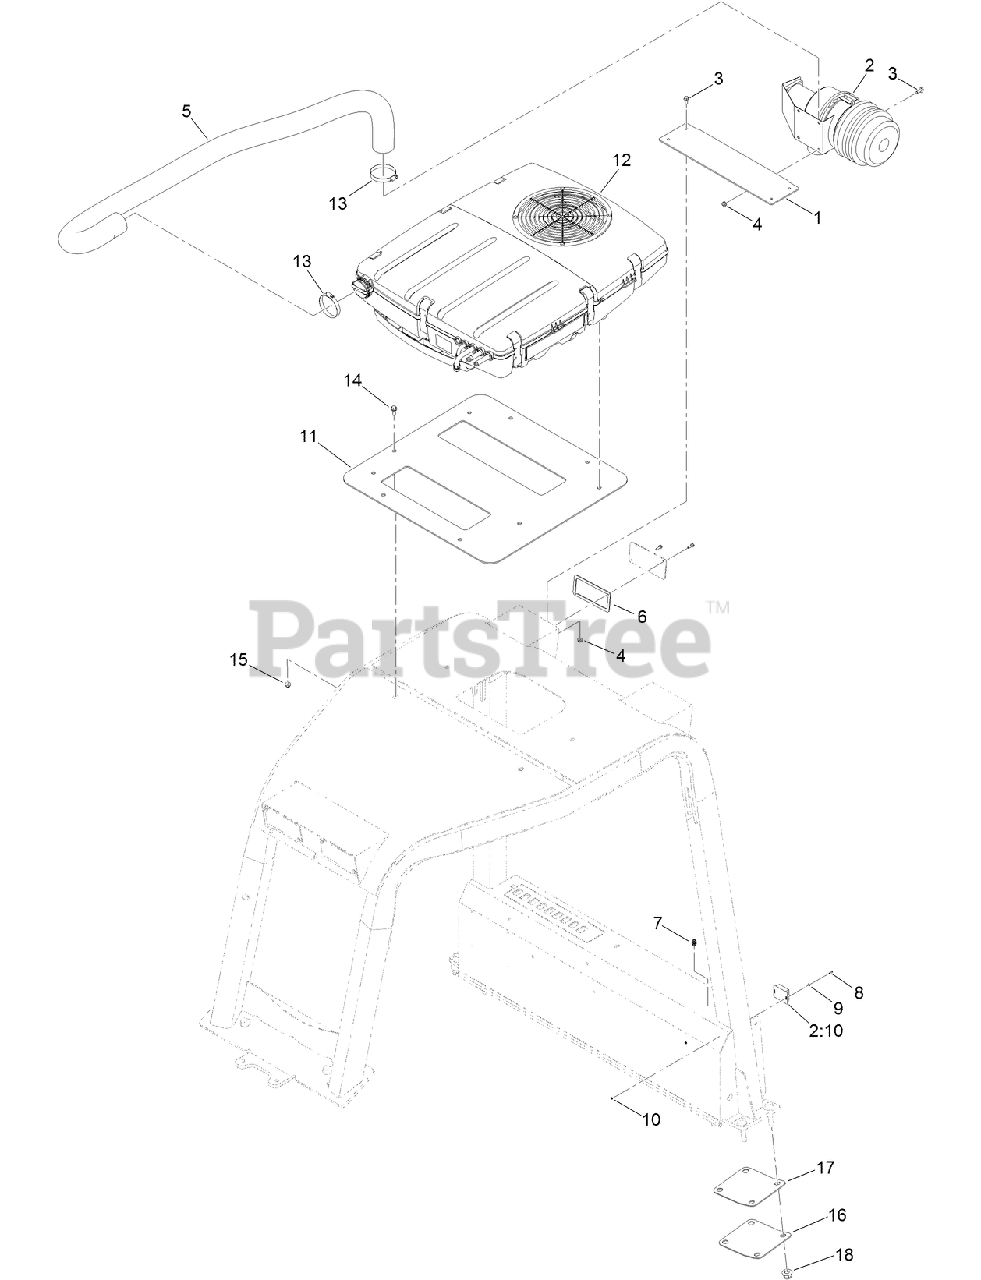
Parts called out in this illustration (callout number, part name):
1	PLATE-PRESSURIZER
2	Automatic Pressure Control ASM
2:10	CONTROL-PRESSURE
3	SCREW-HHF
4	NUT-HF, NI
5	HOSE-PRESSURIZER
6	GASKET-LIGHTS, CAB
7	FITTING-AIR
8	SCREW-HH
9	WASHER
10	NUT-LOCK, NI
11	PLATE-ROOF
12	A/C HEATER ASM
13	CLAMP-HOSE
14	SCREW-HHF
15	NUT-HF, NI
16	PLATE-ROPS COVER
17	FOAM-ROPS SEAL
18	NUT-HHF
